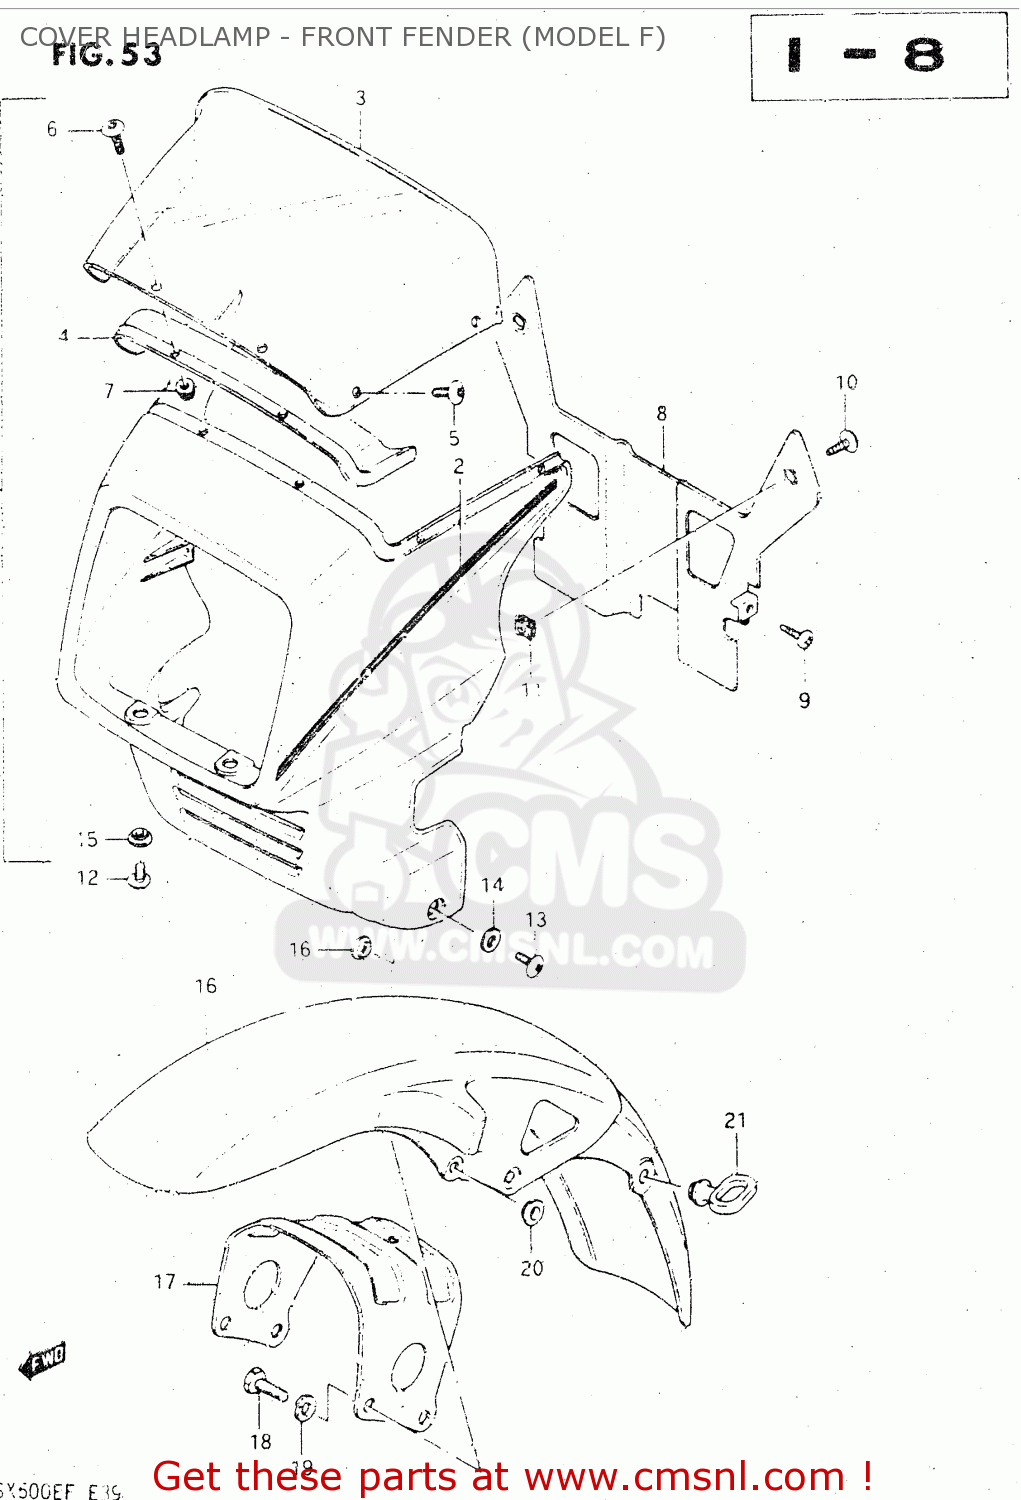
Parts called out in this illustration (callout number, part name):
1	COVER ASSY, HEADLAMP
2	TAPE SET,HEADLAMP
3	WINDOW,COVER HEADLAMP
4	COVER,HEADLAMP,UPPER
5	SCREW(5X12)
6	SCREW
7	NUT
8	PLATE,HEADLAMP COVER
9	SCREW
10	SCREW
11	NUT
12	SCREW 6X12
13	SCREW 6X12
14	WASHER (6.5X18X1.6)
15	WASHER
16	FENDER,FRONT
17	BRACE,FRONT FENDER
18	BOLT
19	LOCK WASHER
20	WASHER
21	GUIDE,CABLE
